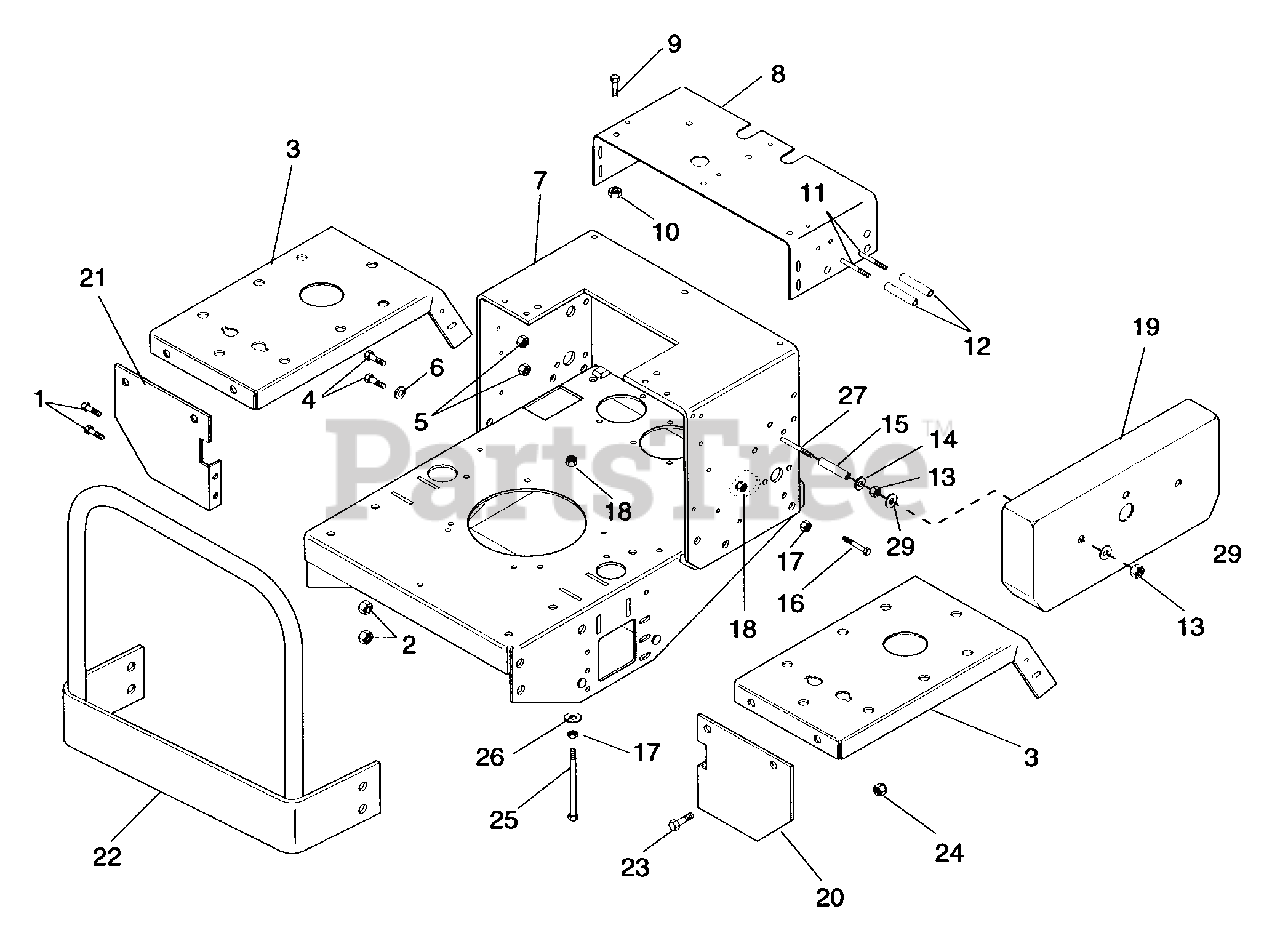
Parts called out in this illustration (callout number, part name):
1	Blt-Hex .38-16 X 1.25 PL GR 5
2	Nut-Lk-Nyl .375-16 PL
3	Fender
4	Blt-Hex .25-20 X .75 PL
5	Nut-Lk-Nyl .250 - 20 PL
6	Wshr-Fl-Stl .281 X .625 X .065
7	Wldmt, Frame PM100
8	Panel, Silkscreen
9	Blt-Hex .38-16 x 1.00 PL GR 5
10	Nut - Lk Nyl .375 - 16 PL
11	Blt-Hex 5/16 - 18 X 3.75
12	Spacer, .328 X .462 X 2.75
13	Nut-Lk-Nyl .312 - 18 PL
14	Wshr-Fl-Stl .344 X .688 X .065 Pl
15	Spacer, .328 X .462 X 2.50 LG
16	Blt-Hex .38 - 16 X 3.00
17	Nut, Hex .375-16
18	Nut-Lk-Nyl .375 - 16 PL
19	Guard Linkage
20	Sprt, Fender R.H.
21	Sprt, Fender L.H.
22	Wldmt, Rear Guard
23	Blt-Hex .31 18 X .75 PL GR 5
24	Nut-Lk-Nyl .312-18 PL
25	Blt-Hex .38 - 16 X 4.00
26	Wshr-Fl-Stl .406 X .812 X .065
27	Blt, Hex 5/16-18 x 3.75
29	Wshr-Fl-Stl .313 x .875 x .065
